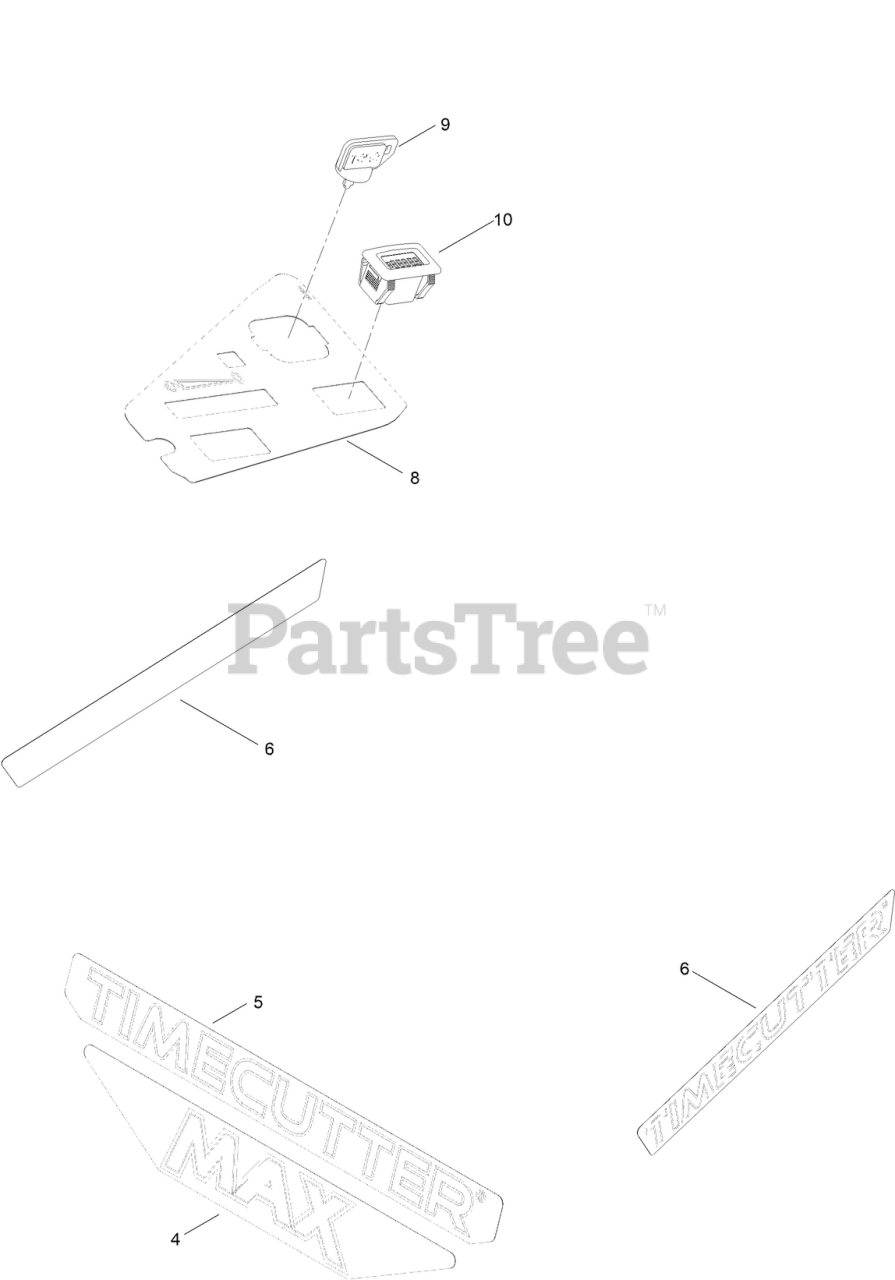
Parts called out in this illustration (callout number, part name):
4	DECAL-MAX
5	DECAL-TIMECUTTER
6	DECAL-TIMECUTTER
8	DECAL - CONTROL PANEL
9	KEY-IGNITION
10	HOUR METER
